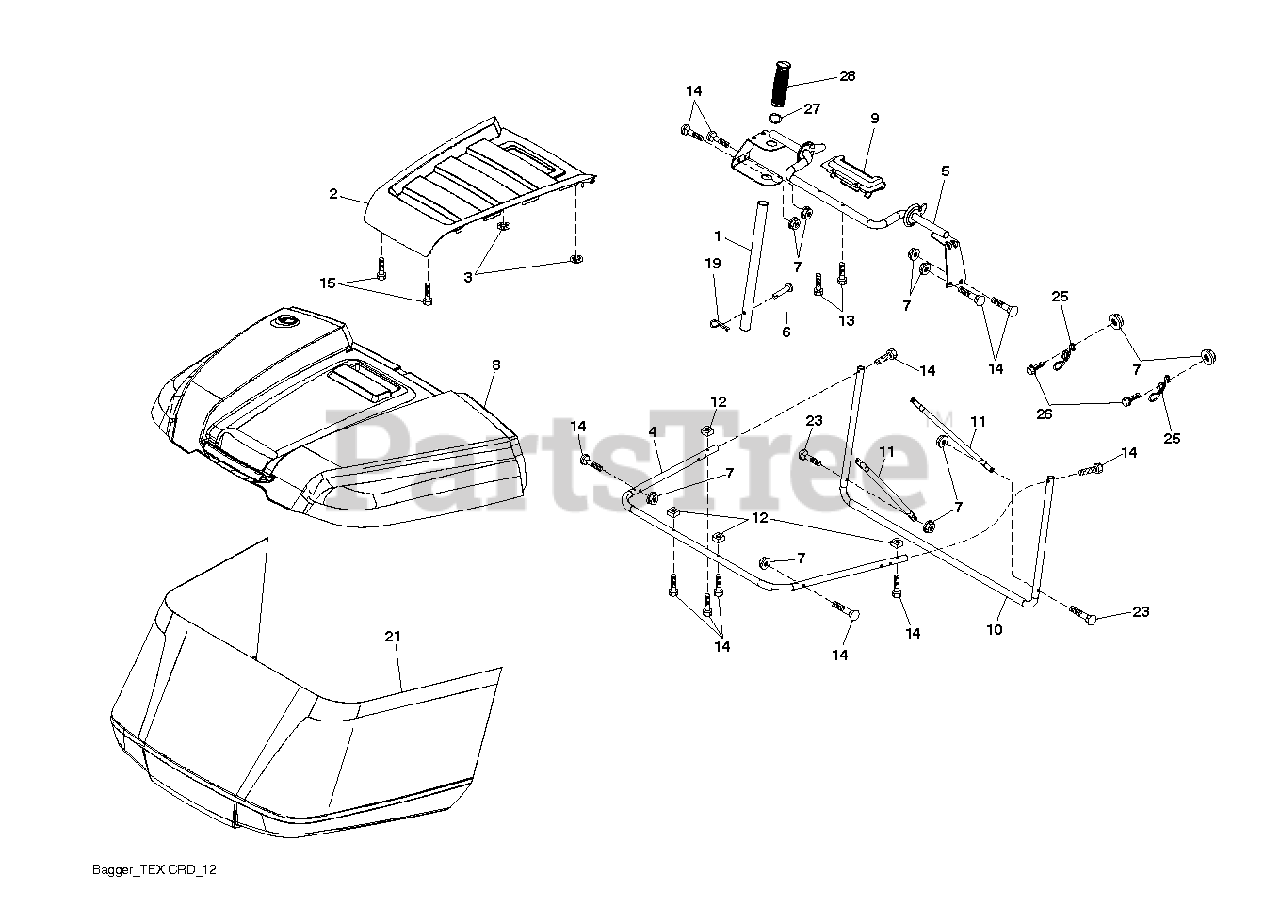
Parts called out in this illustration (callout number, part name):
1	TUBE.HANDLE.BAGGER.CRD/SRD.BLA
2	APPLIQUE.TOP.BAG.SRD.ORANGE
3	NUT.PUSH.156
4	SUBASM.TOP.TUBE.TEX.CRD
5	FRAME.ASM.TOP.BAGGER.SRD
6	RIVET,DRILLED
7	NUT T
8	BAGGER.TOP.SRD.APPLIQUE
9	INSERT.HANDLE.BAGGER.(2 2)
10	FRAME FRAME.FRONT.TEX.CRD
11	BRACE BRACE SIDE TUBE
12	NUT.SQUARE.1/4
13	SCREW.1/4X1.150.HXWSH
14	BOLT.SHOULDER.HX.WSH.1/4X1.150
15	SCREW,#8.FLAT.HEAD.DRILL.TIP
19	PIN.COTTER.5/16.BOW TI
21	BAG SUBASM. TEX CRD GEN 2 HUSQ
25	SPRING.LATCH.BAGGER.SRD
26	SCREW HEX CRT
27	RB GROMMET.RUBBER.SRD
28	GRIP.HANDLE.BLACK
